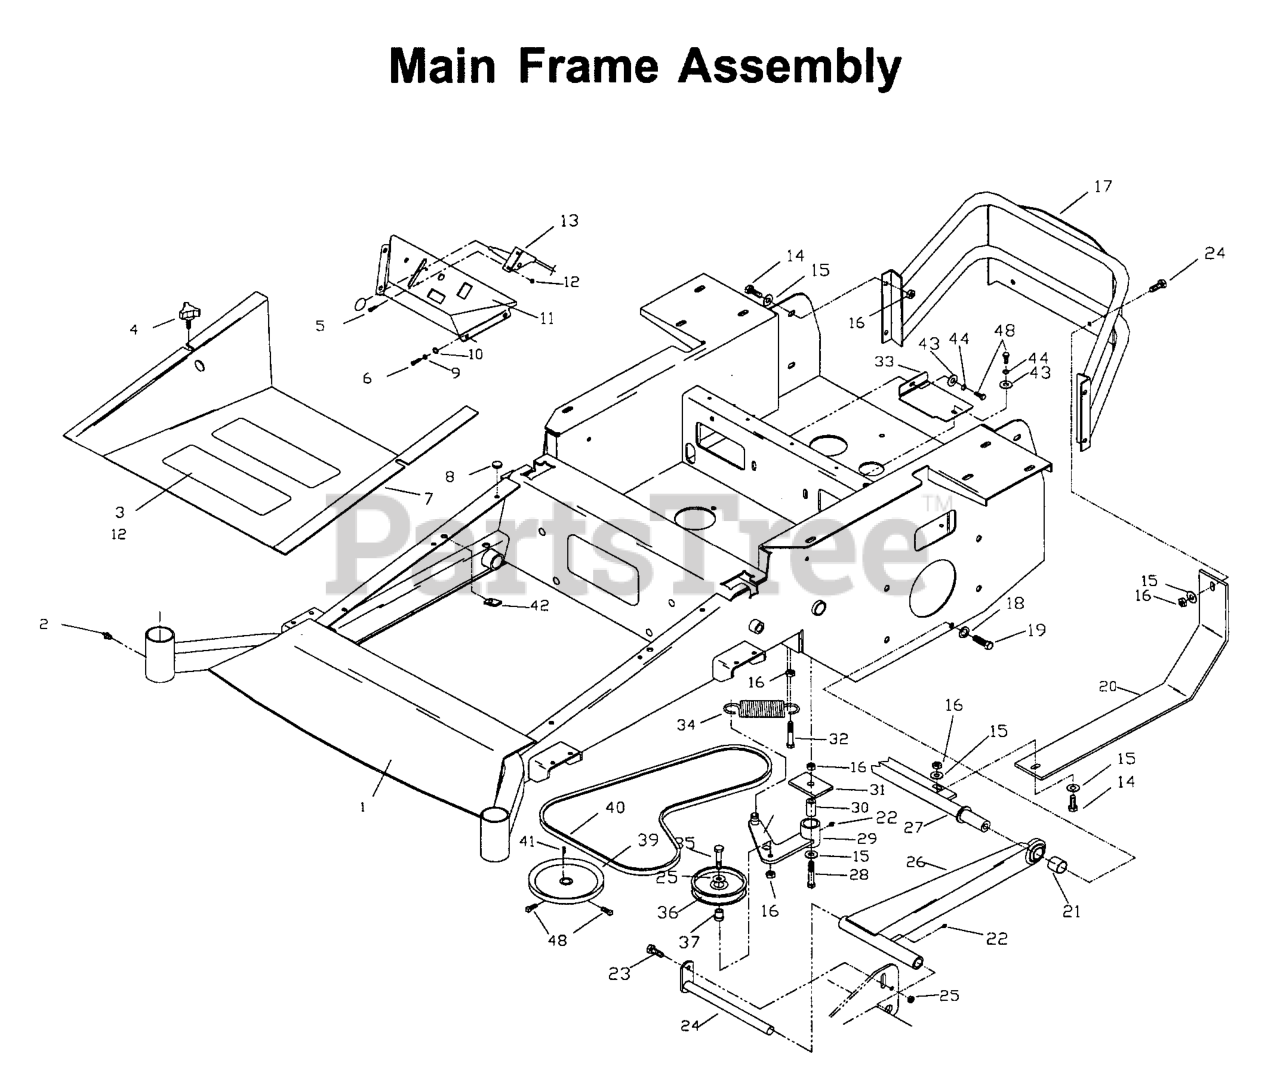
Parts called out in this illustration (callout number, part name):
1	MAIN FRAME W/DECALS
3	ANTI-SKID PAD
4	KNOB W/STUD
5	HCS #10-24 X 1/2
6	SCREW 1/4 X 5/8
7	FOOT PLATE WIDMT
8	GROMMET, BUMPER
9	LOCKWASHER 1/4"
10	WASHER 1/4 FLAT
11	CONSOLE W/DECALS
12	NUT 10-24 NYLOC
13	THROTTLE CONTROL W/BALL KNOB
14	HCS 3/8-16X1.GRD.5.ZD
15	WASHER 3/8 FLAT
16	NUT 3/8C CENTERBLOCK
17	REAR GUARD
18	WASHER 7/16 LOCK
19	HEX SCREW 7/16-14 X 1 GR8
20	SKID PLATE
21	SPACER, STRUT
22	ZERK
23	HCS 5/16C X 3/4
25	NUT 5/16C CENTERLOCK
27	CROSS SHAFT WLD 72
28	HCS 1/2C X 3 1/4
29	IDLER ARM WLDT
30	PIVOT BUSHING
32	HCS 3/8C X 1 1/2
33	IDLER COVER
35	HCS 3/8-16 X 1 3/4 GR5
36	IDLER PULLEY
37	BUSHING, IDLER FLANGE
38	SCREW 5/16C X 5/8 SQ HEAD
40	PUMP BELT
41	KEY 5 MM SQ X 25 MM
42	U-CLIP 5/16-18 NUT RETAINER
43	WASHER 5/16 FLAT
44	WASHER.LOCK.HVY.HLCL.SPR.5/16
45	STRUT WELDMENT
46	STRUT PIN RH
47	STRUT SPACER - 72"
48	HCS 5/16C X 1
539104332	CROSS SHAFT WLDMT
539105886	FRAME 52" & 61"
